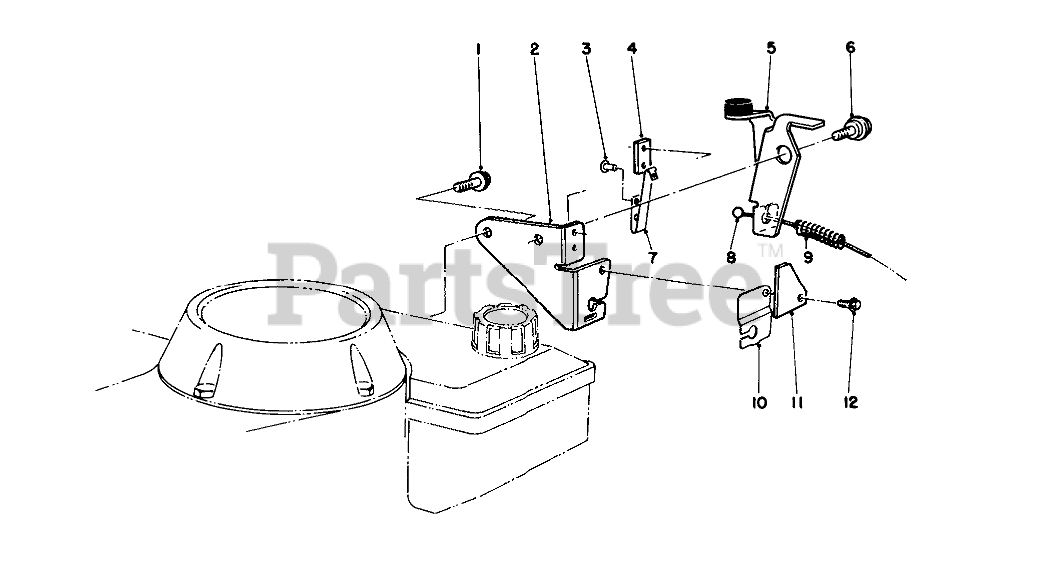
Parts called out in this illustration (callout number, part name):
1	THO FORM SCREW M6 X 1
2	Plate-Mounting
3	RIVET-PLASTIC
4	Strap-Insulation
5	BRAKE PLATE ASM
6	Screw-Shoulder
7	STRAP-GROUND
8	BRAKE CABLE
9	SPRING-COMPRESSION
10	CABLE CLAMP
11	STOP-GROUND STRAP
12	SCREW
